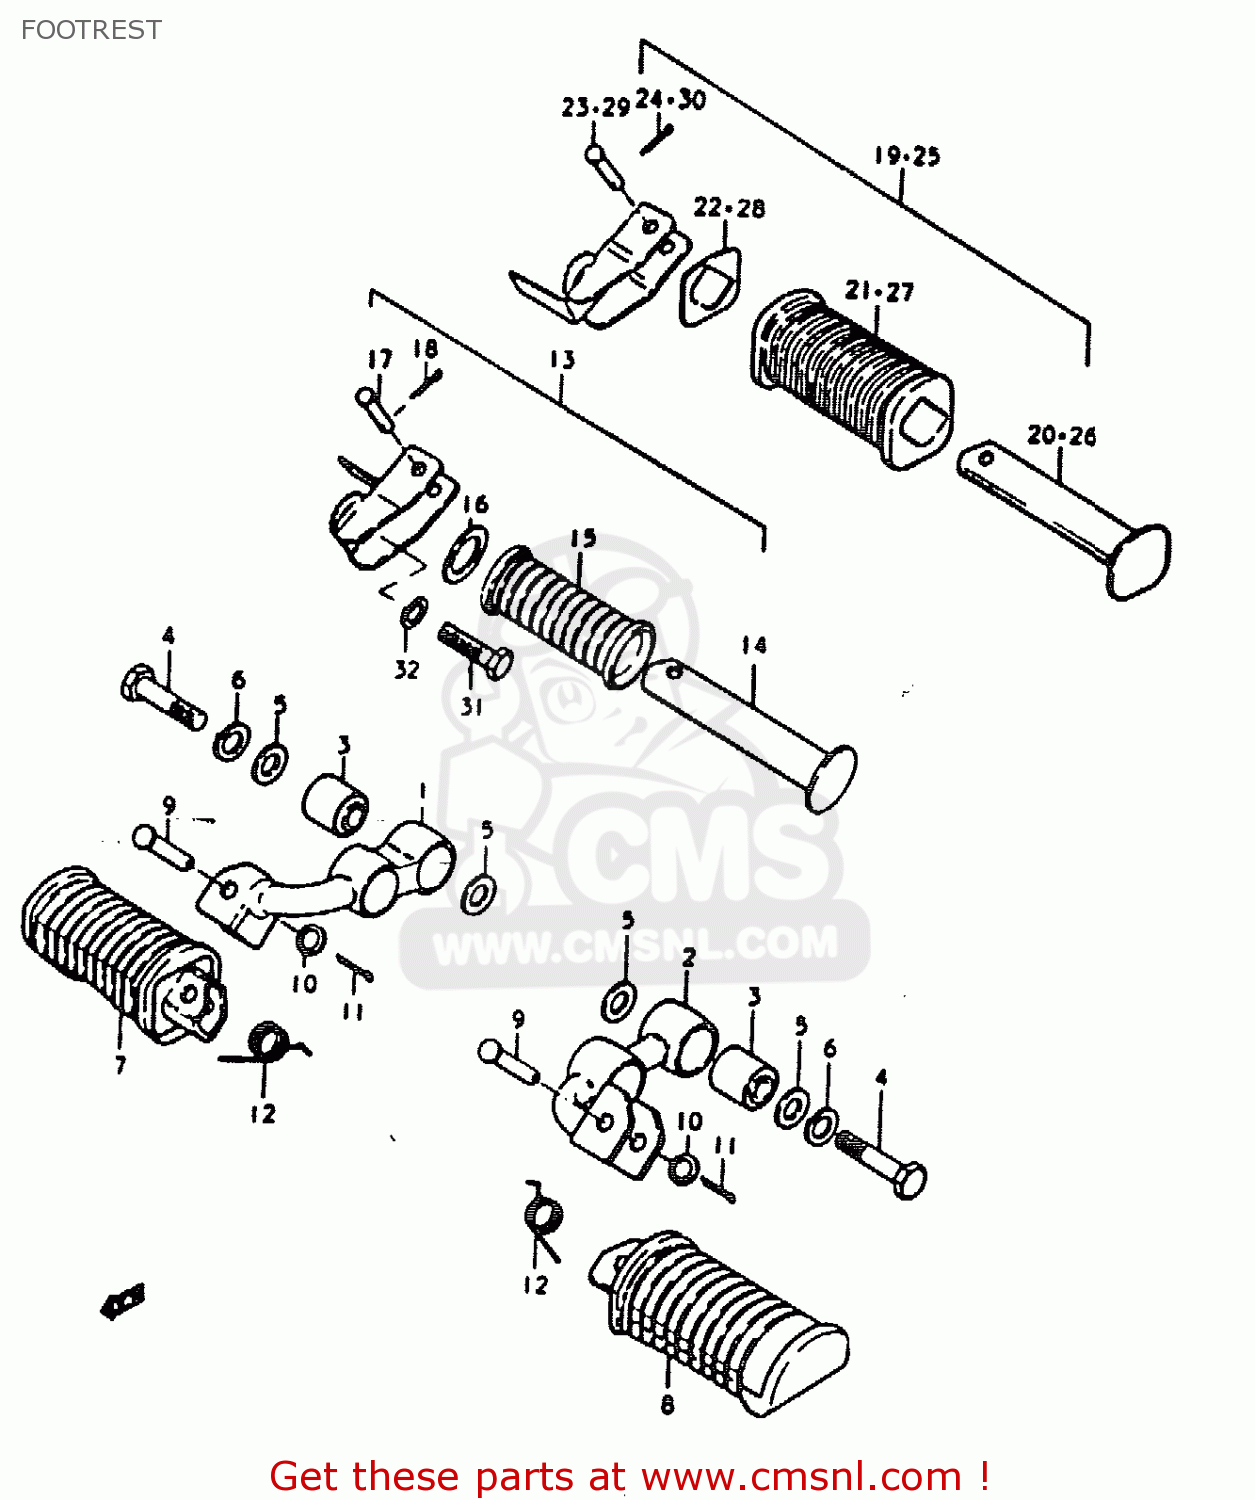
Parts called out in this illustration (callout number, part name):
1	BAR,FRONT FOOTREST
2	BAR,FRONT FOOTREST,LEFT
3	BUSH
4	BOLT
5	WASHER (10.1X21X2.3)
6	LOCK WASHER
7	RUBBER,FRONT FOOTREST
8	FOOTREST
9	PIN
10	WASHER
11	PIN 20X20
12	SPRING
13	FOOTREST ASSEMBLY,REAR
14	BAR,FOOTREST RUBBER
15	RUBBER,PILLION FOOTREST
16	WASHER (19.5X32X2)
17	PIN
18	PIN 20X20
31	BOLT 10X30
32	LOCK WASHER
